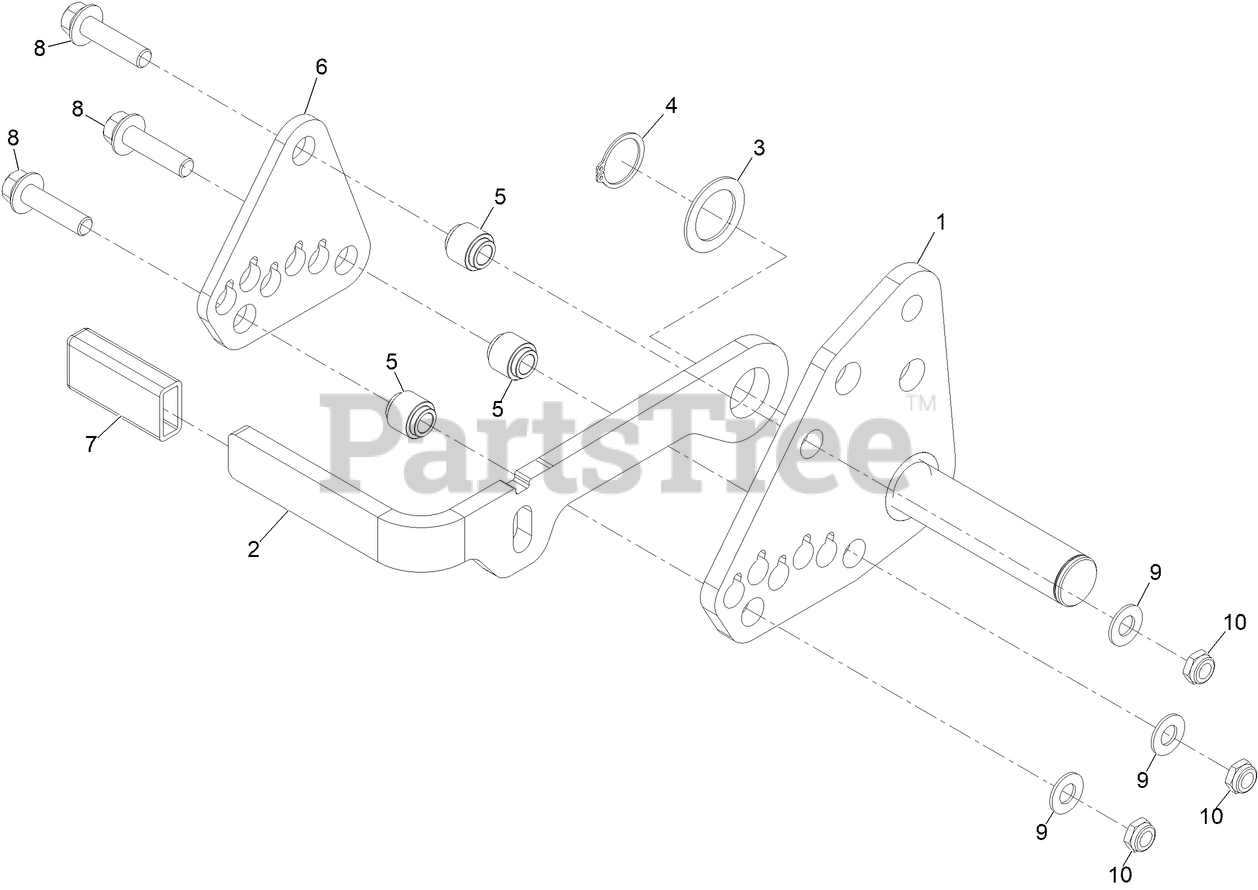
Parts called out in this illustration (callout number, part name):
1	PIVOT ASM-LH HOC
2	LEVER-RAKE, DECK
3	WASHER-THRUST
4	RING-RETAINING
5	SPACER-DOUBLE STEP
6	PLATE-RAKE ADJ, OUTER
7	GRIP-FLAT
8	SCREW-HHF
9	WASHER-PLAIN
